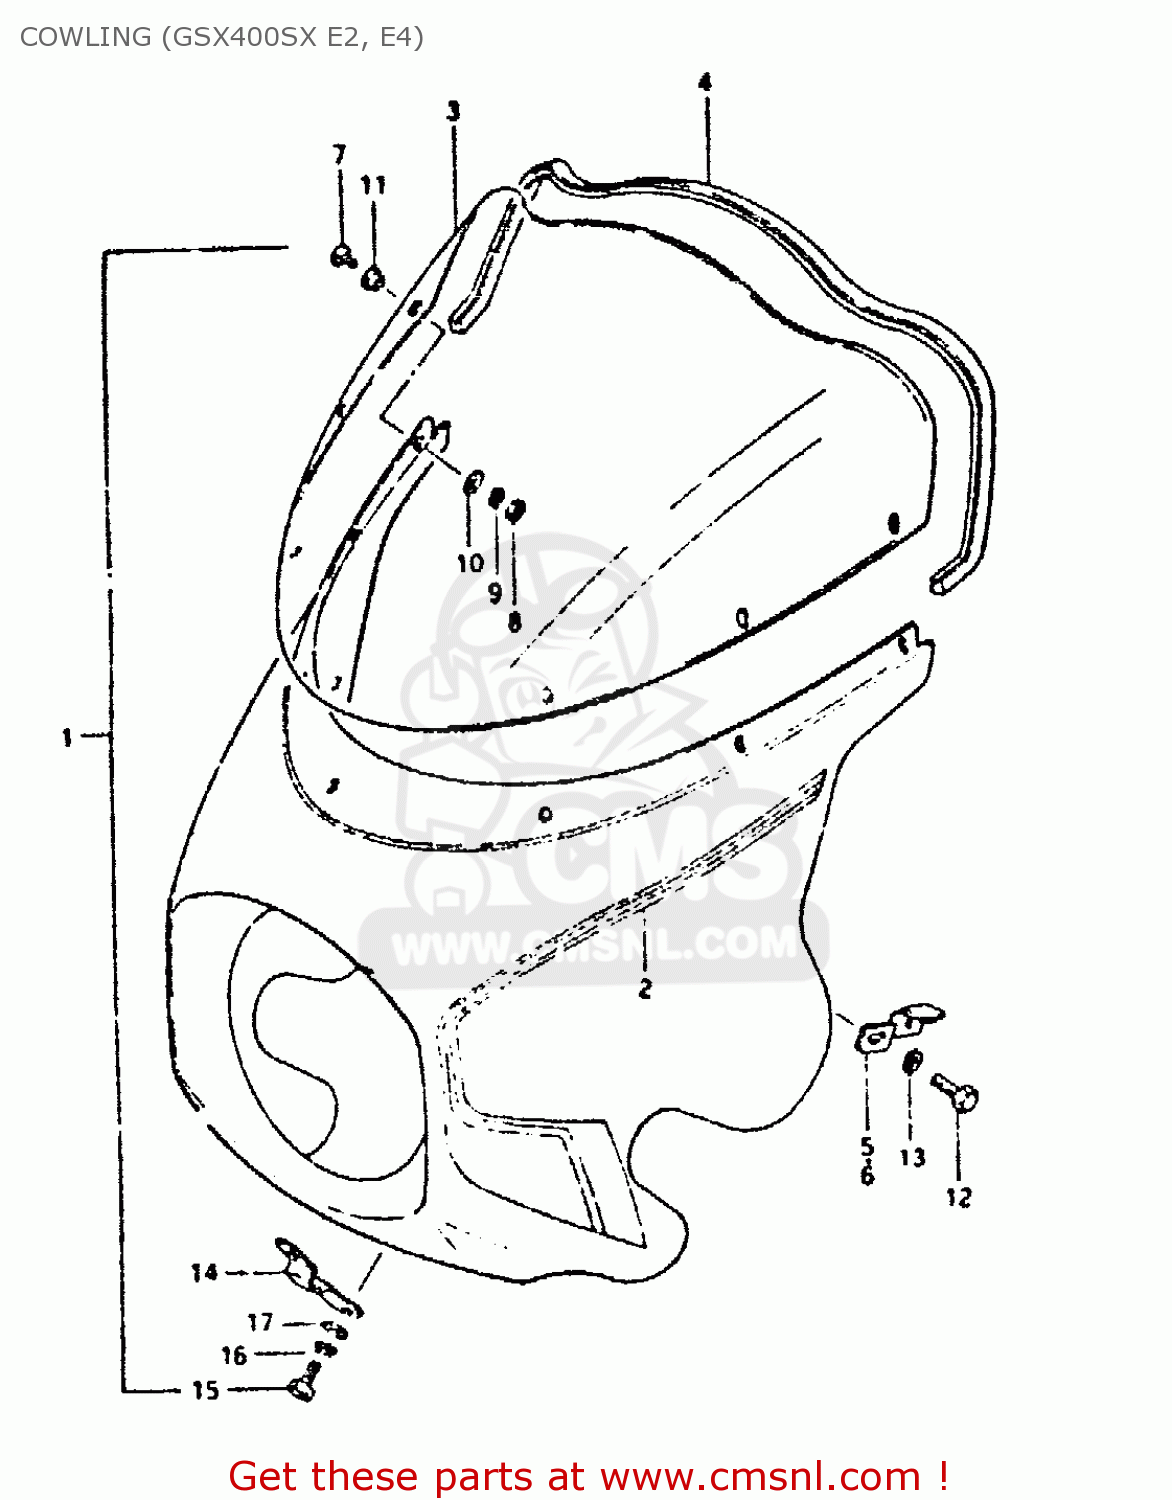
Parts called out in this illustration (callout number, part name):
1	COWLING ASSY
2	TAPE SET
3	WINDOW, COWLING
4	MOLD,COWLING
5	BRACKET,COWLING,RIGHT
6	BRACKET, LH
7	SCREW M5X12 DIN 7985/N
8	NUT
9	LOCK WASHER
10	WASHER
11	CUSHION
12	BOLT
13	LOCK WASHER
14	BRACKET,COWLING,LOWER
15	BOLT
16	LOCK WASHER
17	WASHER
